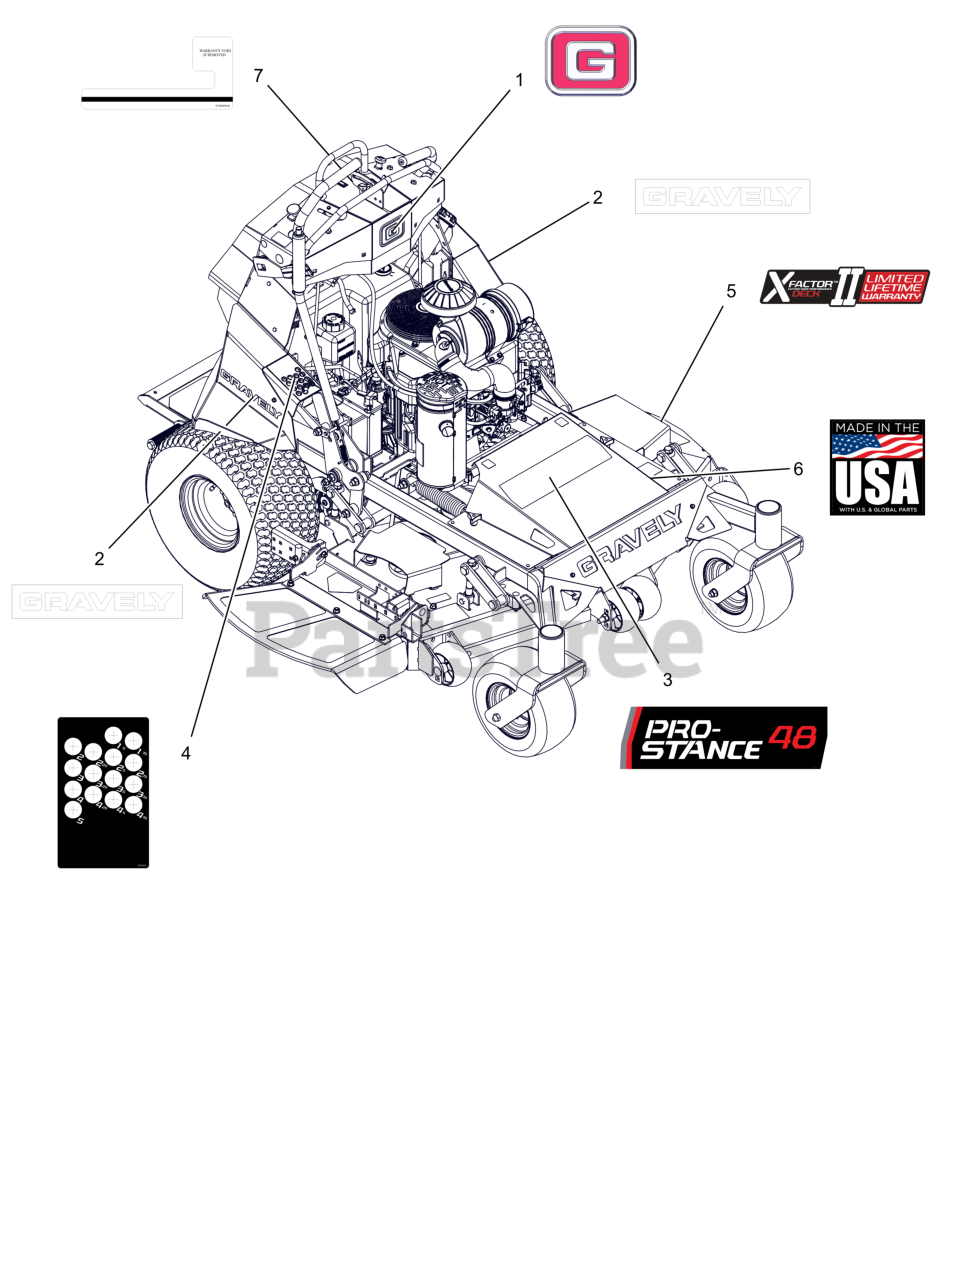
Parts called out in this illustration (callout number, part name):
1	DECAL, GRAVELY BRAND
2	DECAL, 9.5" GRAVELY LOGO
3	DECAL, PROSTANCE 48
4	DECAL, DECK - HEIGHT ADJUST
5	DECAL, X-FACTOR DECK
6	DECAL, MADE IN USA
7	DECAL,HOURMETER - SECURITY
